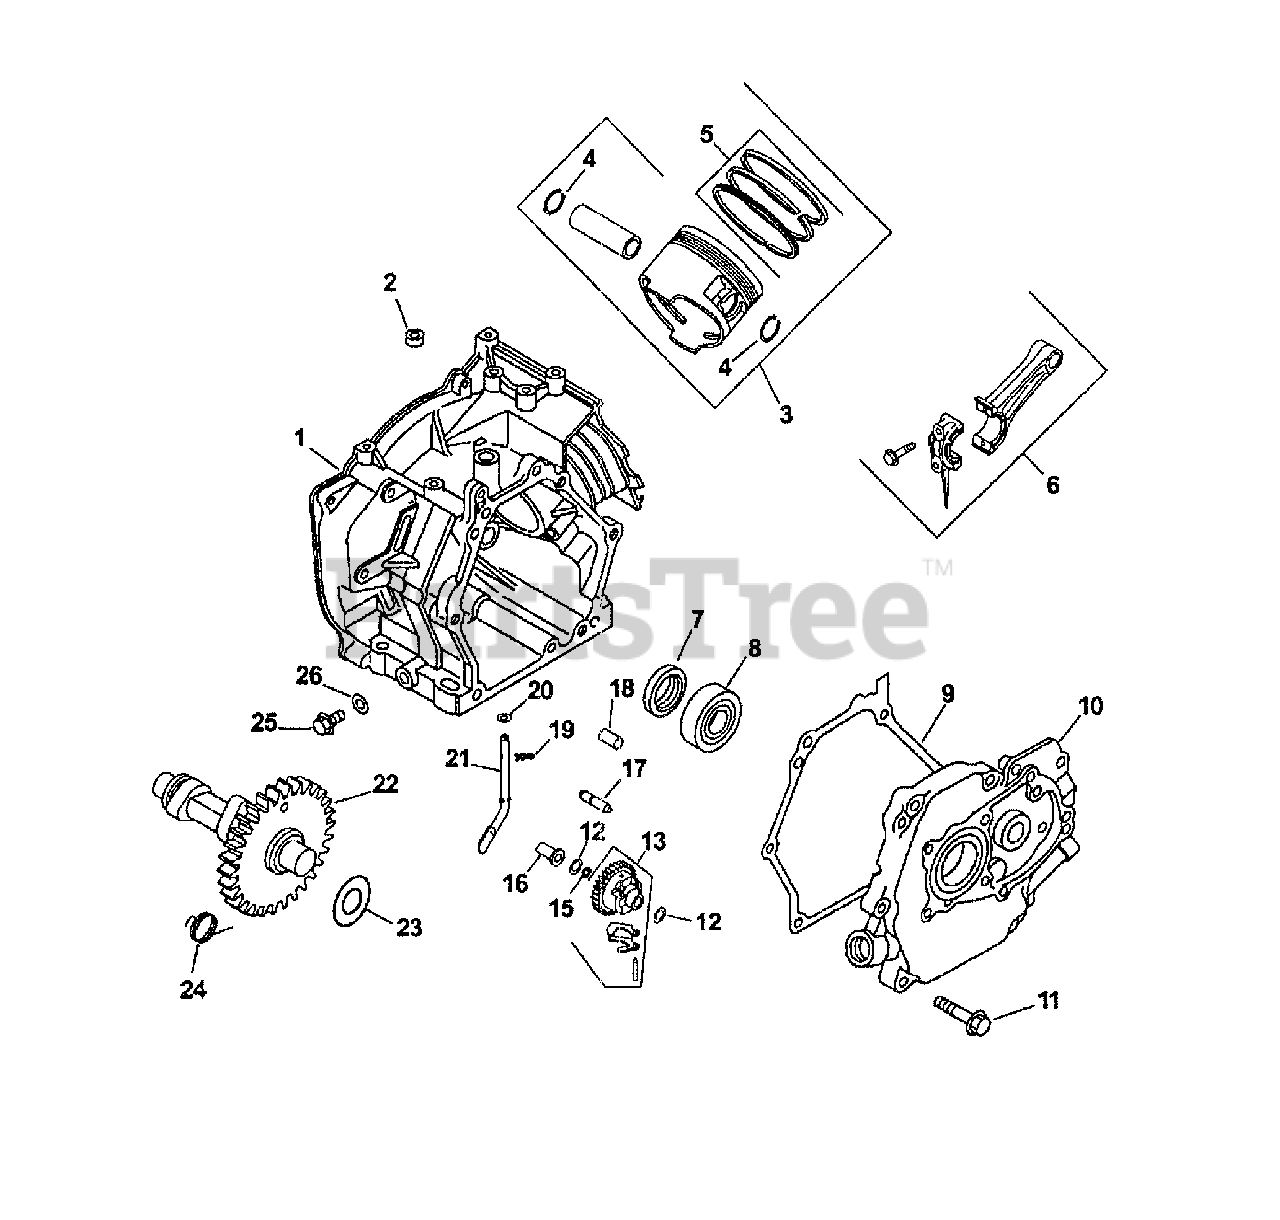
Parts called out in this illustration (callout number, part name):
2	Seal, Governor Shaft
3	Piston w/ring set std.
4	Retainer, Piston Pin
5	Ring Set std.
6	Rod, Connecting
9	Gasket, Closure Plate
10	Plate, Closure
11	Screw, Closure Plate
13	Governor Gear
17	Shaft, Governor
21	Cross Shaft, Governor
